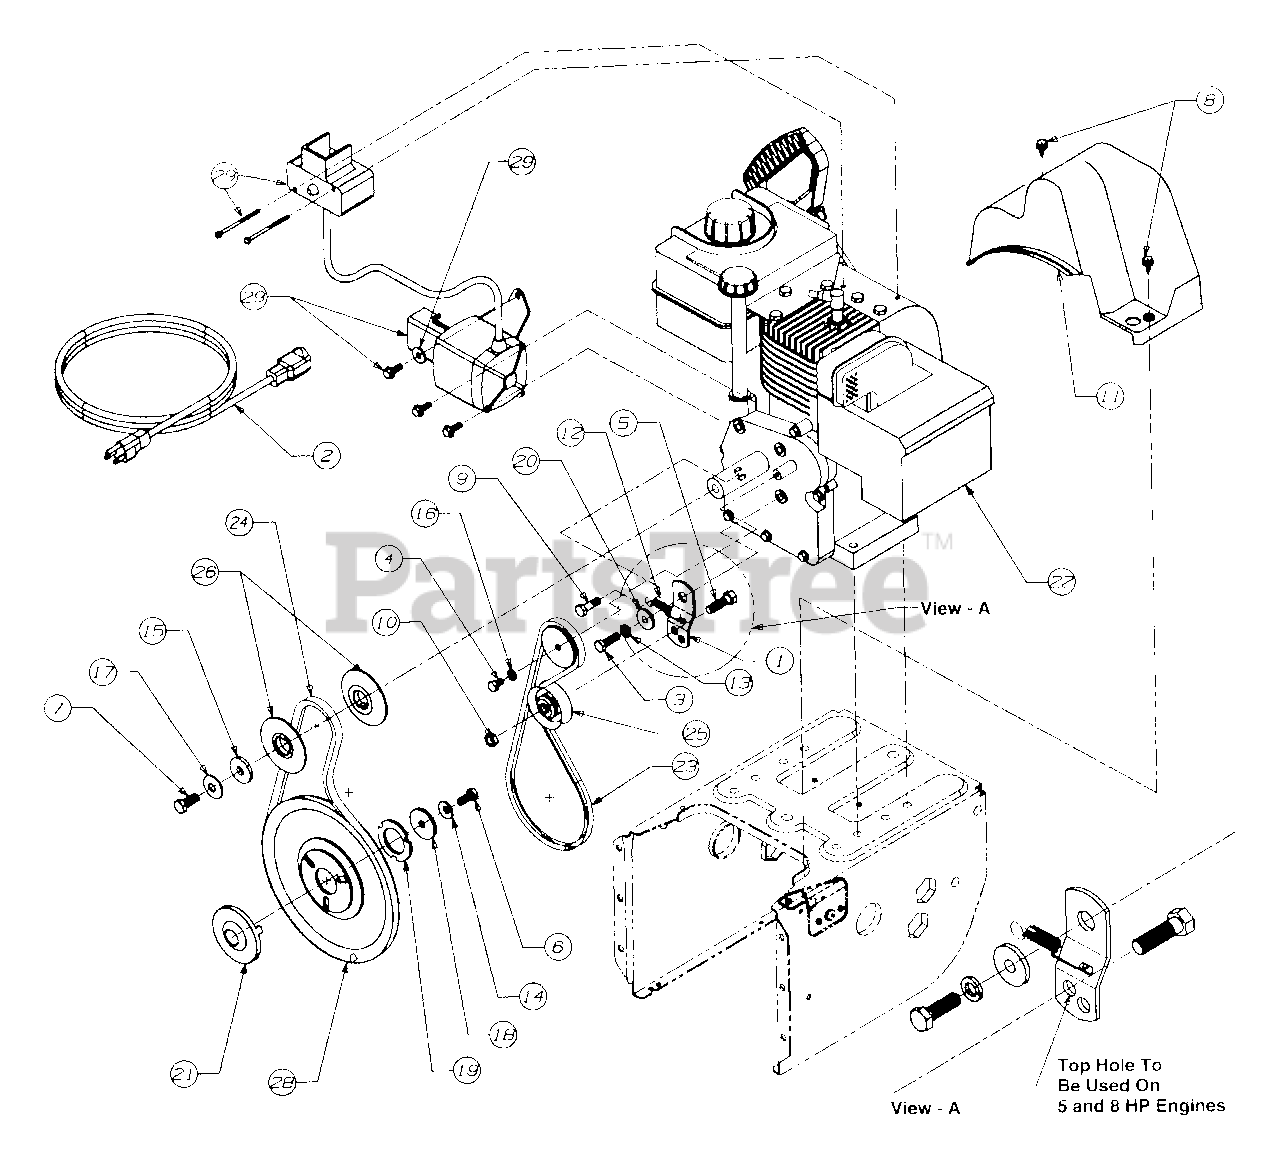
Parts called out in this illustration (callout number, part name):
3	Screw, Hex
4	Hex Screw
5	Screw, Hex
6	Screw, hex
7	Screw, Hex
8	Hex Screw
9	Screw, Hex
10	Hex Jam Nut
11	Belt Cover
12	Spring
13	Lock Washer
14	Washer, Bell
15	Washer, Flat
16	Washer, Lock
17	Washer, Flat
18	Washer, Flat
19	Washer
20	Shoulder Spacer
21	Pulley Adapter
22	Eng., HSSK Tec. 5.0 HP Horz.
23	V-Belt
24	V-Belt
25	Idler, Flat
26	Pulley, Half
28	Pulley, Auger
29	Electric Start Kit
